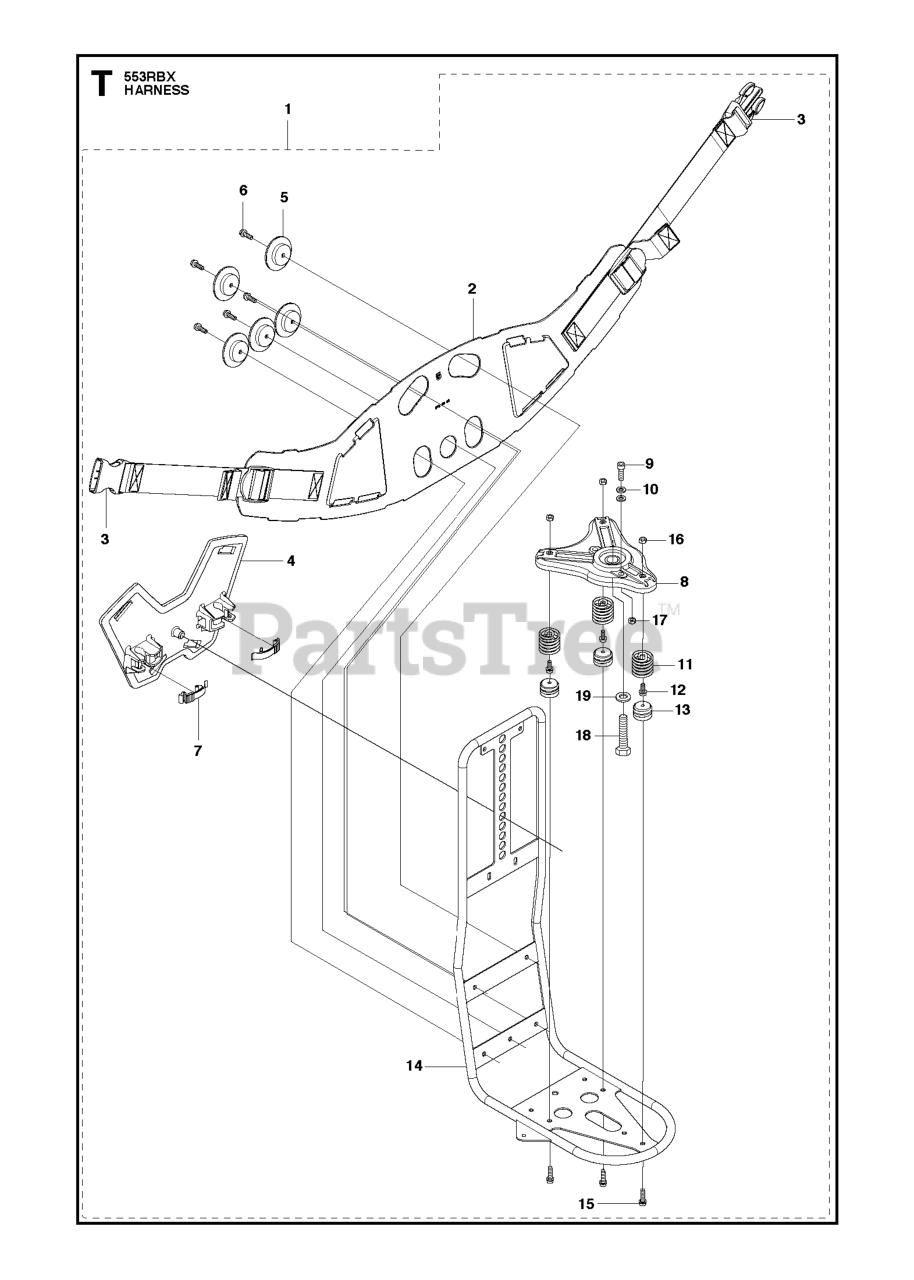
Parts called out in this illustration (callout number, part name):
6	SCREW IHSCFT
9	SCREW IHSCM
18	Screw M10x25
19	WASHER
